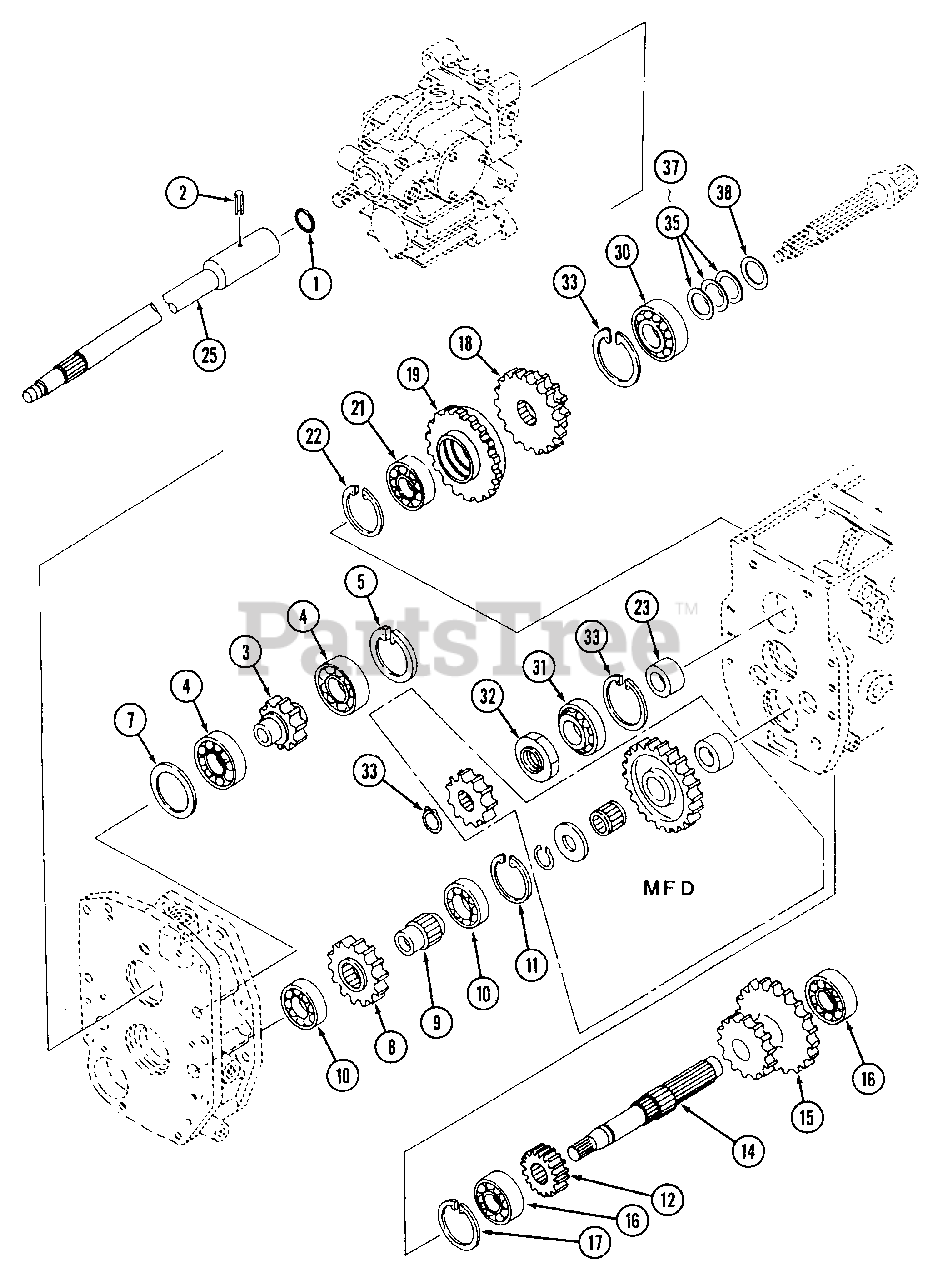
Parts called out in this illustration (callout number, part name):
14	Shaft, Sub Change
25	Shaft, Main
35	Shim
37	Shim
